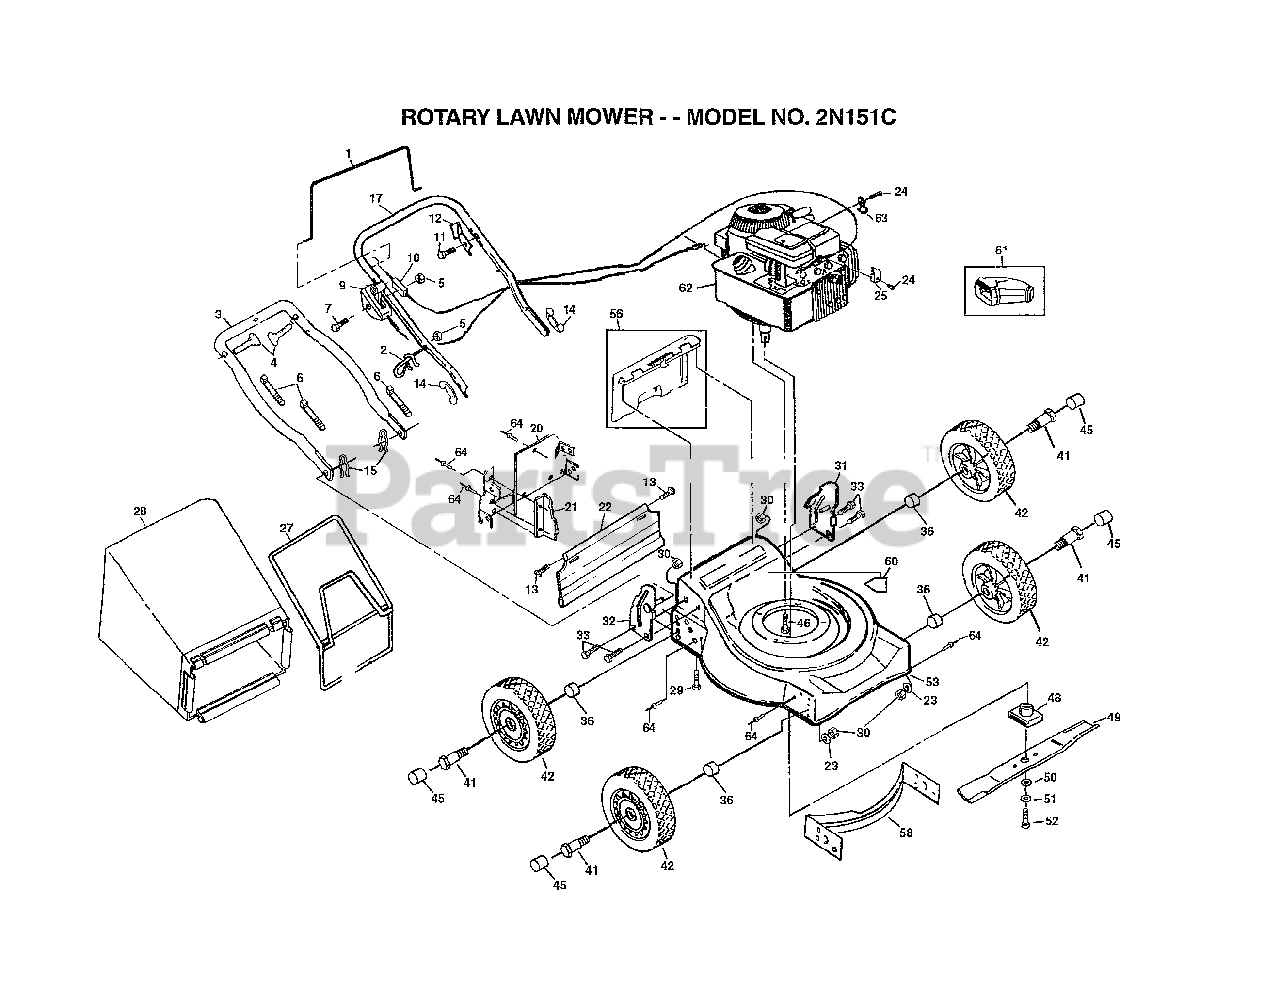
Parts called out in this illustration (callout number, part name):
1	CONTROL BAR PM
2	ROPE GUIDE
4	BOLT.HANDLE.LM
7	SCREW.HXHD.WASH.
9	CONTROL THROTTLE
10	"CABLE,ENG ZONE CO"
11	TAPPING SCREW
12	"BRKT,UPSTOP"
13	HINGE SCREW
14	"NUT,WING PM"
15	HAIRPIN COTTER
20	PLATE.BACK.20RD
22	SKIRT.REAR.20RD.
23	WASHER PM
24	SCREW PM
25	CABLE CLAMP
27	FRAME.CATCHER.ASM
28	GRASS BAG
29	SCREW
30	LOCKNUT PM
33	SCREW
41	AXLE BOLT
42	WHEEL.ASM
45	HUB CAP-PLASTIC
46	SCREW
48	BLADE ADAPTOR
49	BLADE.20.MULCH.AY
50	"WASHER,HARDEN"
51	LOCKWASHER
52	SCREW
56	KIT.DOOR.RR.20STL
60	DECAL HYT
63	GUIDE CLIP PM
64	BLIND RIVET
